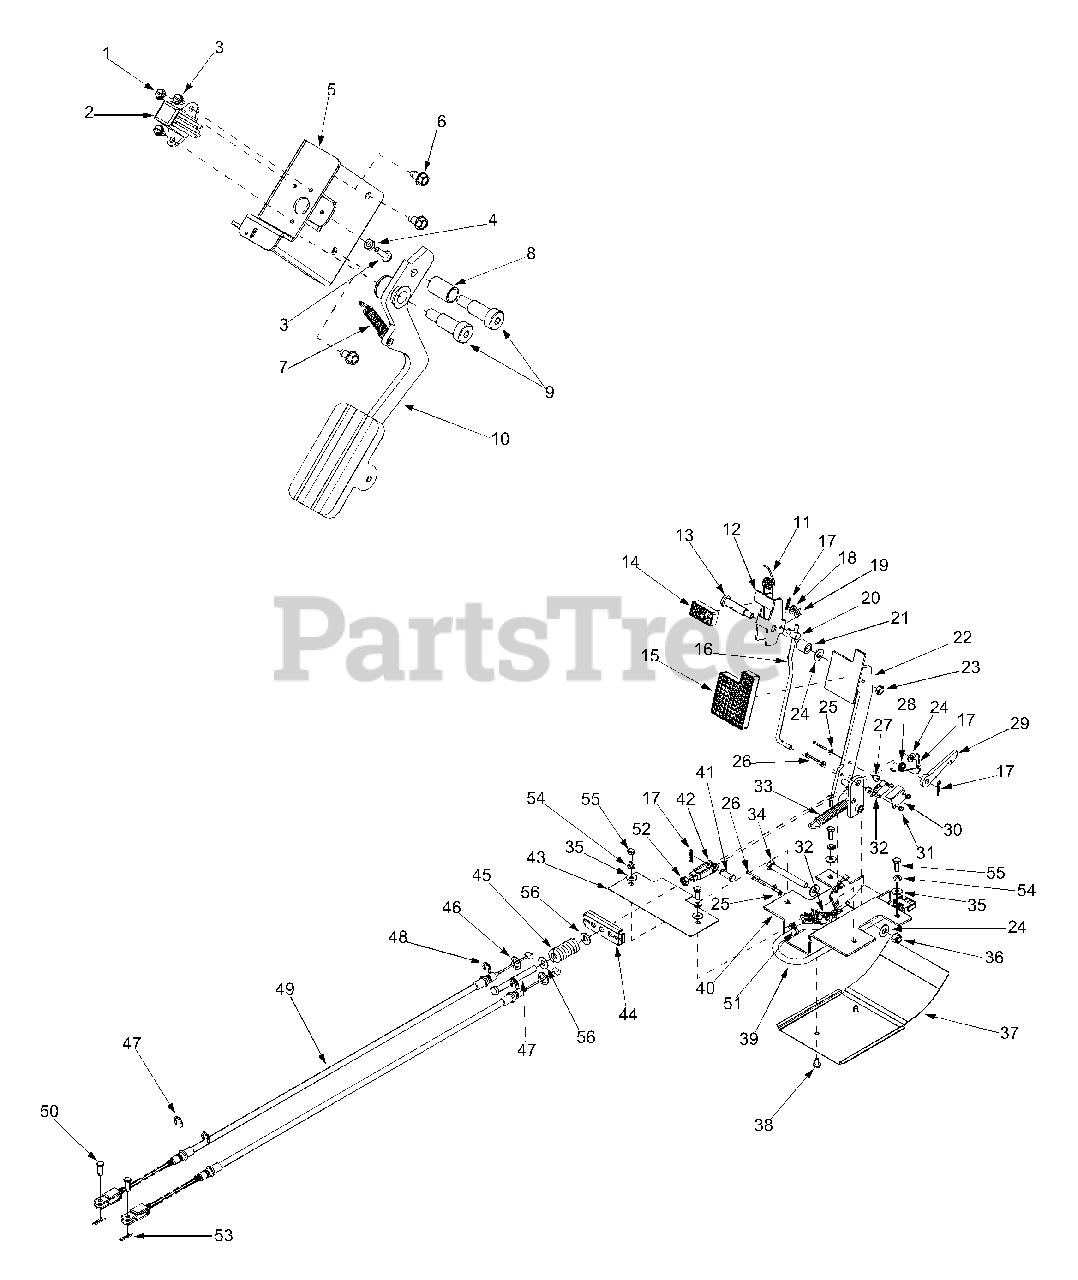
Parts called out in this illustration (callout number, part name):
1	Slotted Hex Screw #10-32 x .75
2	Throttle Sensor
3	Slotted Hex Screw #10-32 x .31
4	Hex Nut #10-32
5	Mounting Pedal Bracket Assembly
6	Hex Washer Screw
7	Extension Spring .38 OD x 2.5 Lg
8	Sleeve Bearing .50 ID x .625 OD
9	Shoulder Screw
10	Accelerator Pedal Arm Assembly
11	Torsion Spring
12	Park Pedal Assembly
13	Shoulder Screw .500 x 1.825
14	Parking Brake Pad
15	Brake Pad
16	Park Brake Adjuster Rod
17	Cotter Pin
18	Flat Washer .330 ID x .630 OD
19	Spring Washer .317 ID x.625 OD
20	Adjustment Ferrule 1/4-20 x 1.0
21	Spacer .510 x .75 x .780 Lg
22	Brake Arm Assembly
23	Lock Jam Nut 3/8-16
24	Flat Washer .406 ID x .875 OD
25	Washer .156 ID x .375 OD
26	Head Screw #4-40 x 1.125
28	Torsion Spring
29	Parking Brake Lock Plate
30	Switch Cover Plate
31	Nut #4-40
33	Extension Spring .59 OD x 4.01 Lg
34	Hex Cap Screw 3/8-16 x 3.25
35	Flat Washer .260 ID x .720 OD x .060
36	Hex Lock Nut 3/8-16
37	Brake Plate Shield
38	Hex Washer Screw 1/4-20 x .500
39	Brake Harness Assembly
40	Brake Mounting Plate
41	Clevis Pin .375 Dia x .969
42	Adjustment Clevis
43	Top Bracket Cover Plate
44	Equalizer Brake Plate
45	Compression Spring 1.0 OD x 2.0 Lg
46	Flat Washer .641 ID x 1.0 OD
47	Hex Cap Screw 3/8-24 x 3.75
48	E Ring .500 Dia
49	Brake Cable
50	Clevis Pin
51	Cable Tie
52	Jam Nut 3/8-24
53	Cotter Pin
54	Lock Washer 1/4
55	Hex Cap Screw 1/4-20 x .875
56	Flat Washer .406 ID x 1.0 OD
